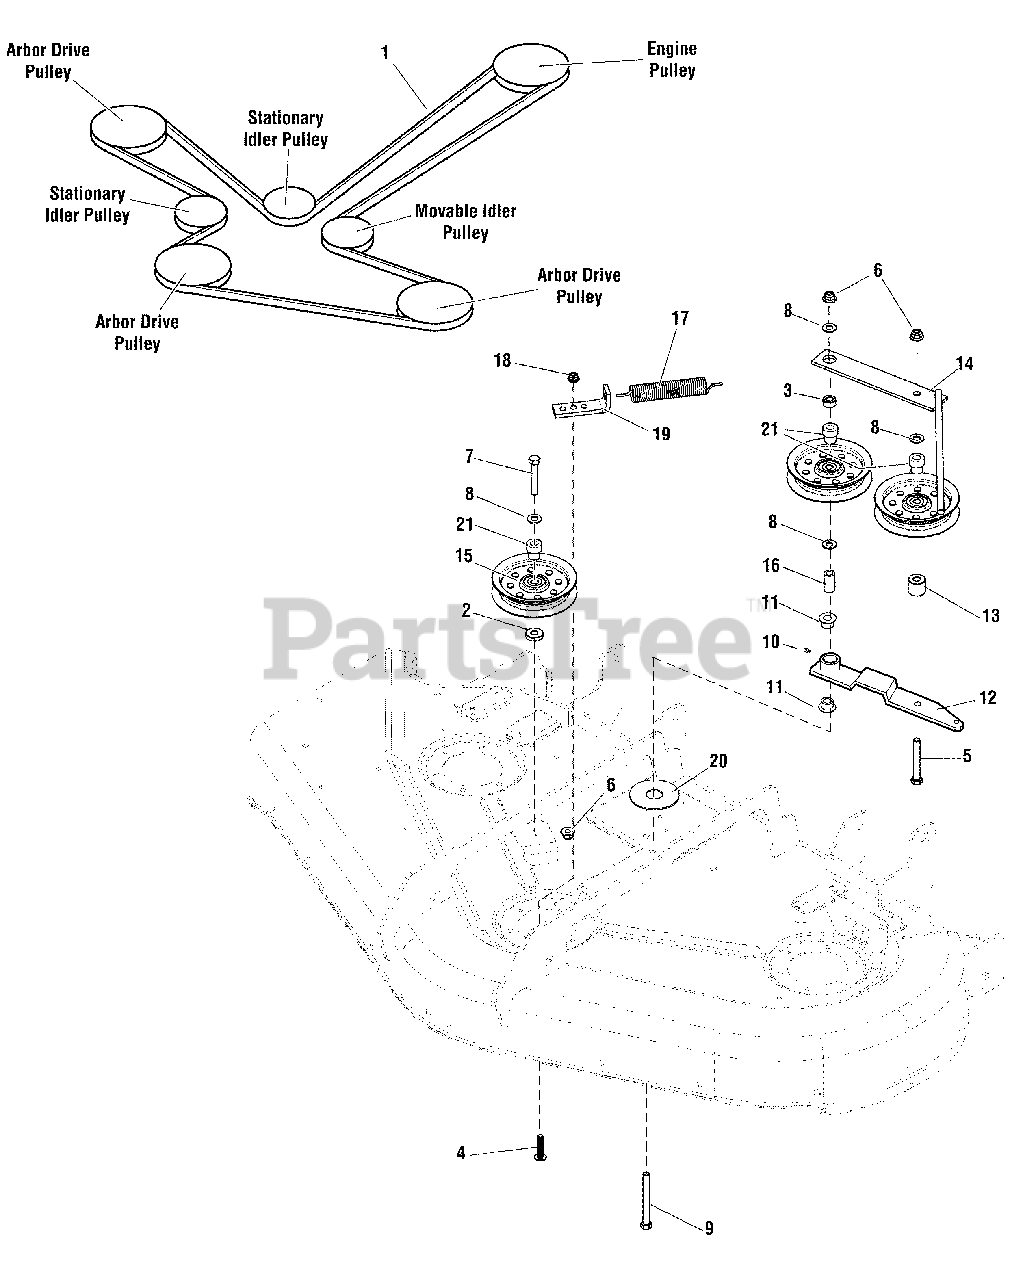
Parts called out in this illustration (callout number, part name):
1	BELT, #7-8055, 155" E.L.
2	SPACER, .39 X 1.00 X .25
3	SPACER, .39 X .75 X .38
4	BOLT, 5/16-18 X 1 1/4 FLANGE
5	BOLT, 3/8-16 X 2-3/4" GD5 YZ
6	NUT, 3/8-16 HEX NYLOCK FLANGE
7	BOLT, 3/8-16 X 2-1/4 GD5 YZ
8	WASHER, 3/8 SAE
9	BOLT, 3/8-16 X 3-1/2 GD5 YZ
10	GREASE FITTING, 1/4-28 STRAIGHT
11	BUSHING, 0.628 ID X 0.751 OD X 0.400 LG PWDR MTL
12	WELD, DECK IDLER ARM, CONSZ - RED
13	SPACER, .39 X 1.00 X .88
14	WELD, MT, IDLER, TENSION
15	PULLEY, IDLER
16	SPACER, 0.39 ID X 0.625 OD X 1.15 LG CASE HARD
17	SPRING, EXTENSION, 1.00
18	NUT, 5/16-18 HEX NYLOCK FLANGE
19	BRACKET, SPRING ANCHOR - RED
20	WASHER, .41 X 1.75 X .14
21	SPACER, HYDRO PULLEY
